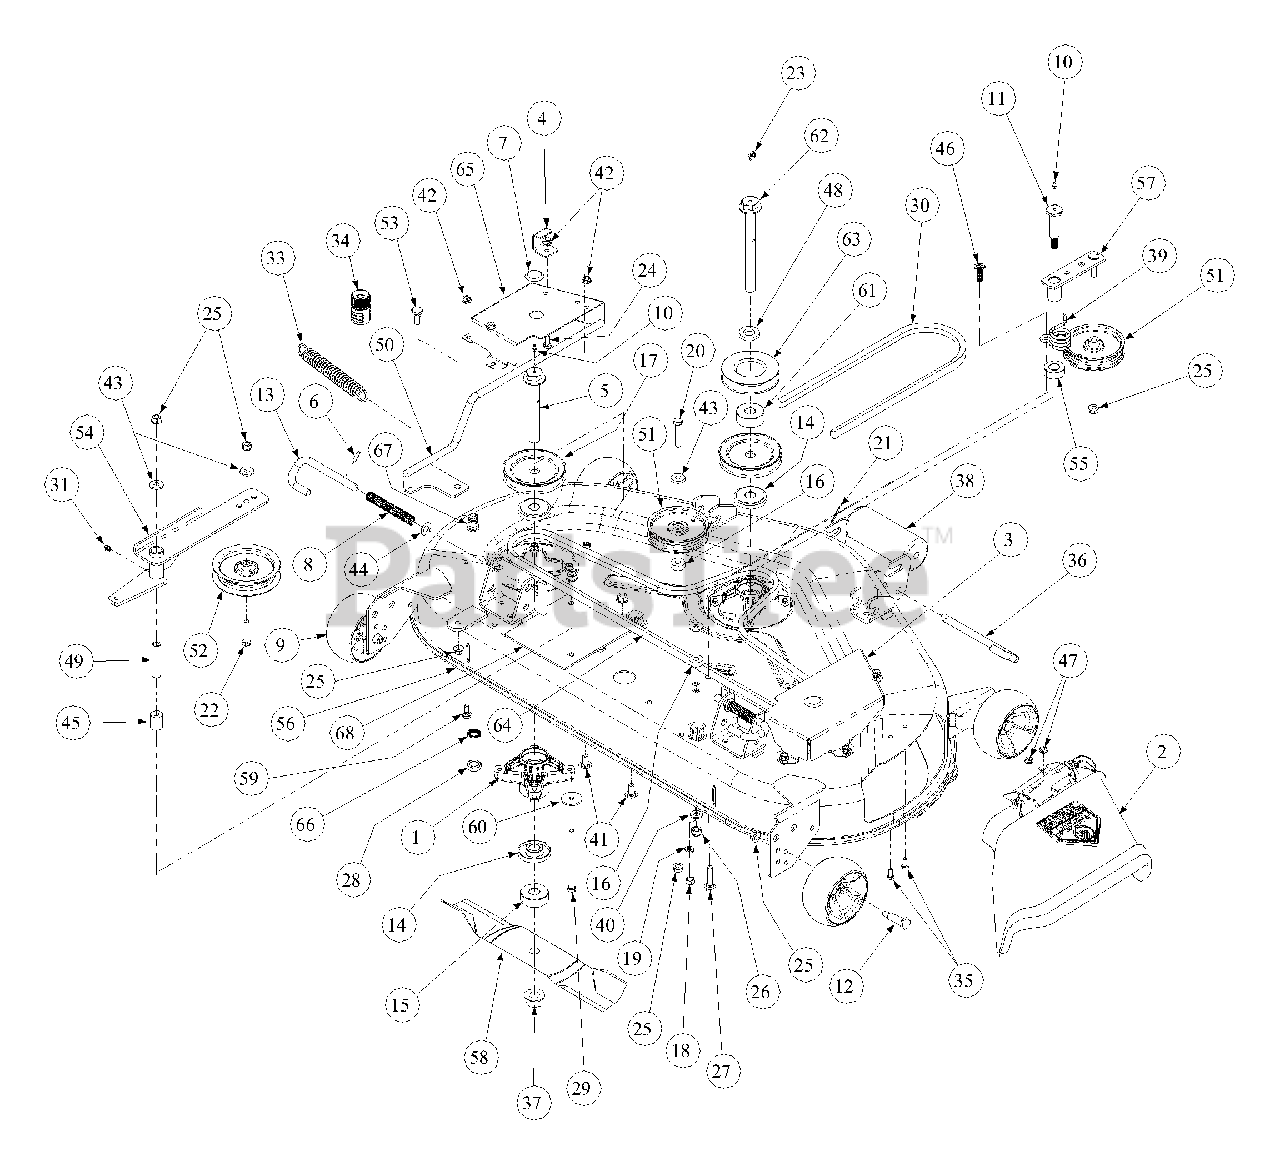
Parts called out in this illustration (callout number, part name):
1	Spindle Assembly
2	Chute Assembly
3	Belt Cover Right Hand
4	Tension Rod Stop Bracket
5	Spindle Bolt 3/4-16 x 5.37
7	Button Plug
8	Compression Spring .63 OD x 6.3
9	Deck Wheel, 5.00 Dia.
10	Grease Fitting
11	Shoulder Screw .68 x 2.11
12	Shoulder Screw .498 x 1.53
13	Support Pin
14	Spindle Spacer
15	Blade Spacer
16	Spacer .406 ID x 1.0 OD
18	Hex Nut 3/8-16
19	Lock Washer, 3/8
20	Hex Cap Screw 3/8-16 x 2.00
21	Cotter Pin .125 Dia x 1.0
22	Capscrew, 3/8-16 x 1-3/4
23	Grease Fitting, 1/4-28, 90 degree
24	Hex Cap Screw 5/16-18 x .75
25	Hex Nut, 3/8-16, Flange Lock
26	Nut 7/16-14, Nylock
27	Carriage Bolt 3/8-16 x 1.50
28	Hex Nut, M16-1.5
29	Hex Cap Screw 3/8-16 x 5.00
30	V-Belt, B-Section
31	Grease Fitting, 1/4-28 x 3/16
32	Idler Washer
33	Extension Spring, 1.0 OD x 5.00
34	Water Nozzle Adaptor
35	Hex Cap Screw 1/4-20 x .620
36	Roller Pin 1/2 x 7.31
37	Nut, 3/4-16, Hex Flange
38	Front Roller
39	Idler Spring
40	Flat Washer, .469 ID x .875 OD x .105
41	Carriage Bolt, 3/8-16 x .75
42	Lock Nut 5/16-18 Hex Flange
43	Flat Washer, .406 ID x 1.0 OD x .105
44	Flat Washer .508 ID x 1.0 OD
45	Spacer, .39 ID x .875 OD x 1.100
46	Carriage Screw, 3/8-16 x 1.25
47	Nut, 1/4-20, hexflange Lock
48	Spacer .812 ID x .218
49	Spacer, .39 ID x .625 OD x 2.75
50	Deck Handle Weldment
51	Flat Pulley
52	Idler Pulley, 4.06 OD
53	Shoulder Screw, .50 x .27 Lg., 3/8-16
54	Idler Arm Assembly, Top
55	Spacer .760 ID x 1.5 OD
56	Deck Assembly 44"
57	Idler Arm Assembly
58	Blade
59	Self Tapping Screw 5/16-18 x .750
60	Washer, 5/16-18
61	Spacer .760 ID x 2.00 OD x 0.790
62	Spindle Bolt 3/4-16 x 7.155
63	V-Pulley 4.25 OD Casting
64	V-Belt, A-Section
65	Belt Cover Left Hand
66	Lock Washer, 17 x 23.8 x 1.95
67	Deck Water Nozzle
68	Deck Plate
